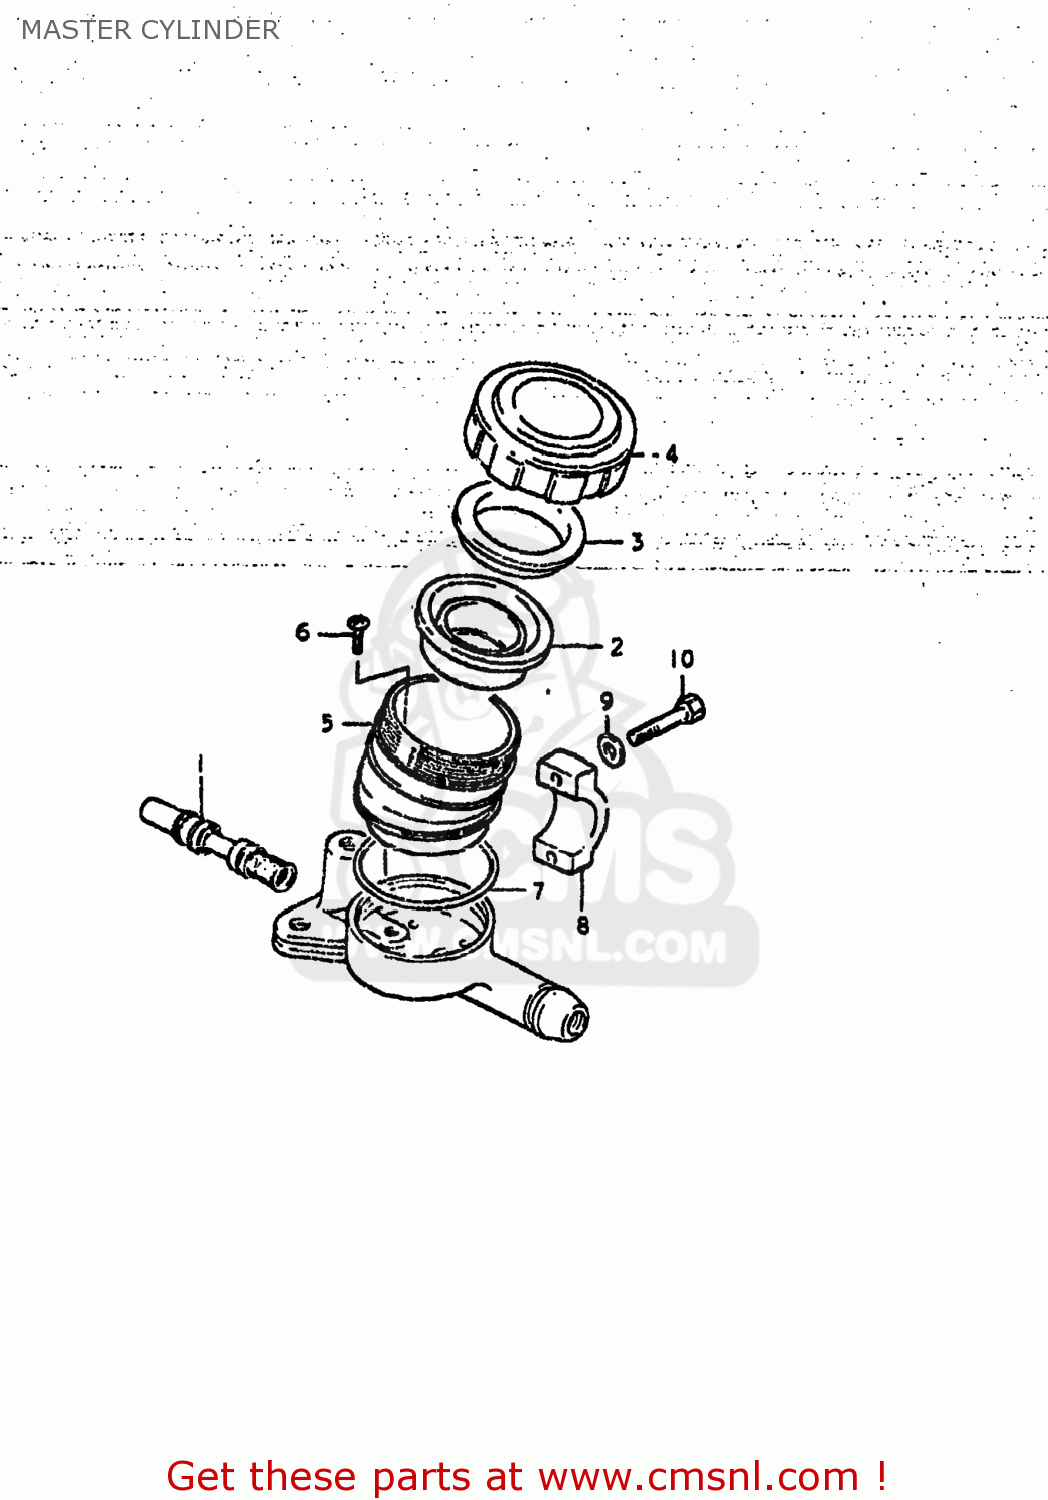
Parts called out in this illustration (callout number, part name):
1	CUP SET,MASTER CYLINDER
2	DIAPHRAGM
3	PLATE,DIAPHRAGM
4	CAP
5	RESERVOIR
6	SCREW,MASTER CYLINDER
7	O RING
8	HOLDER,MASTER CYLINDER
9	WASHER
10	BOLT
